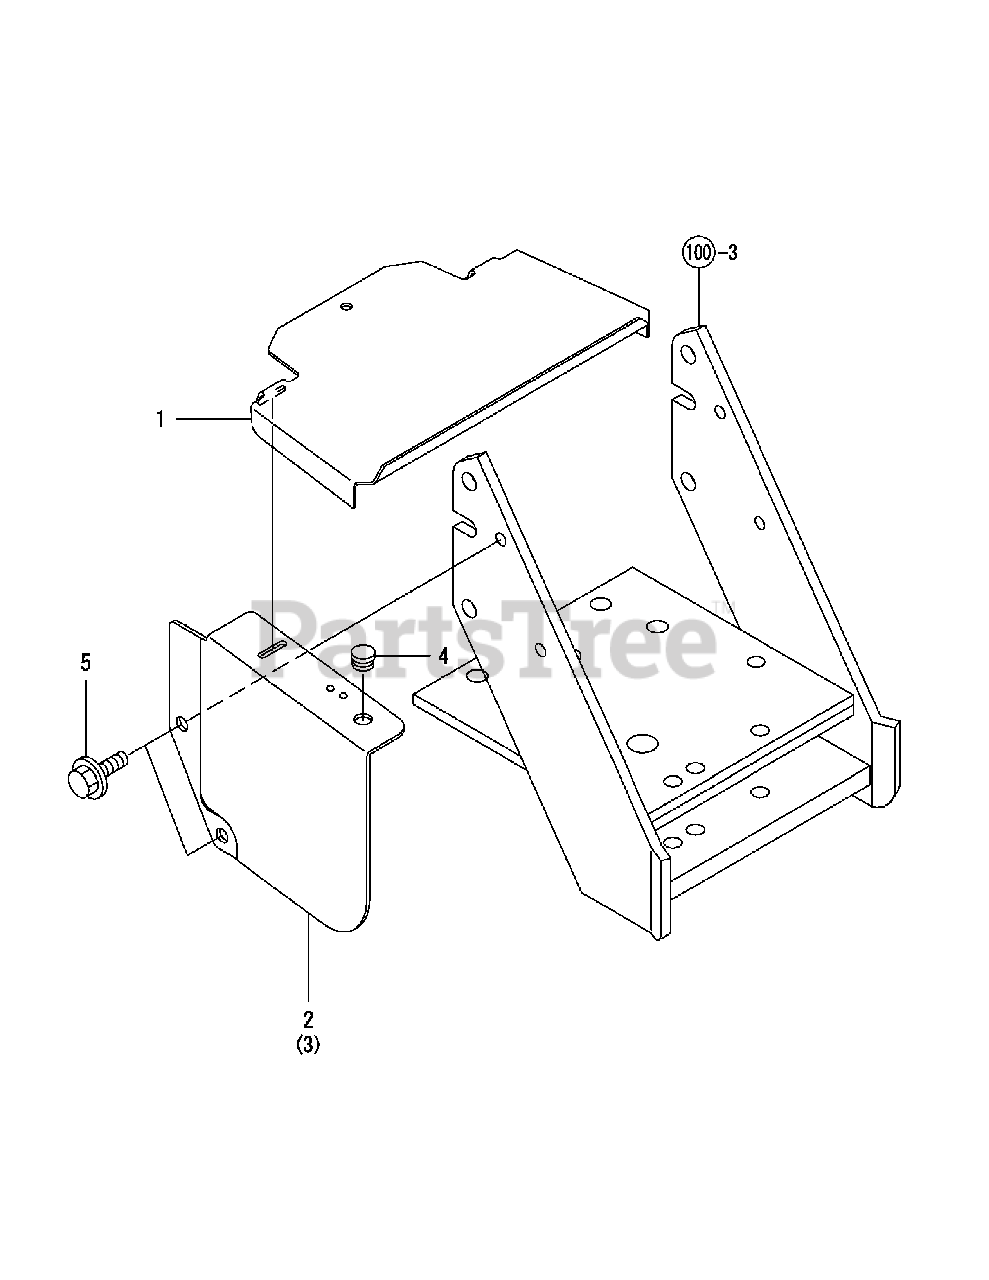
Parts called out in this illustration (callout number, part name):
1	GUARD ASSY, PTO
2	BRACKET, GUARD L.H.
3	BRACKET, GUARD R.H.
5	BOLT M10X 16 PLATED
